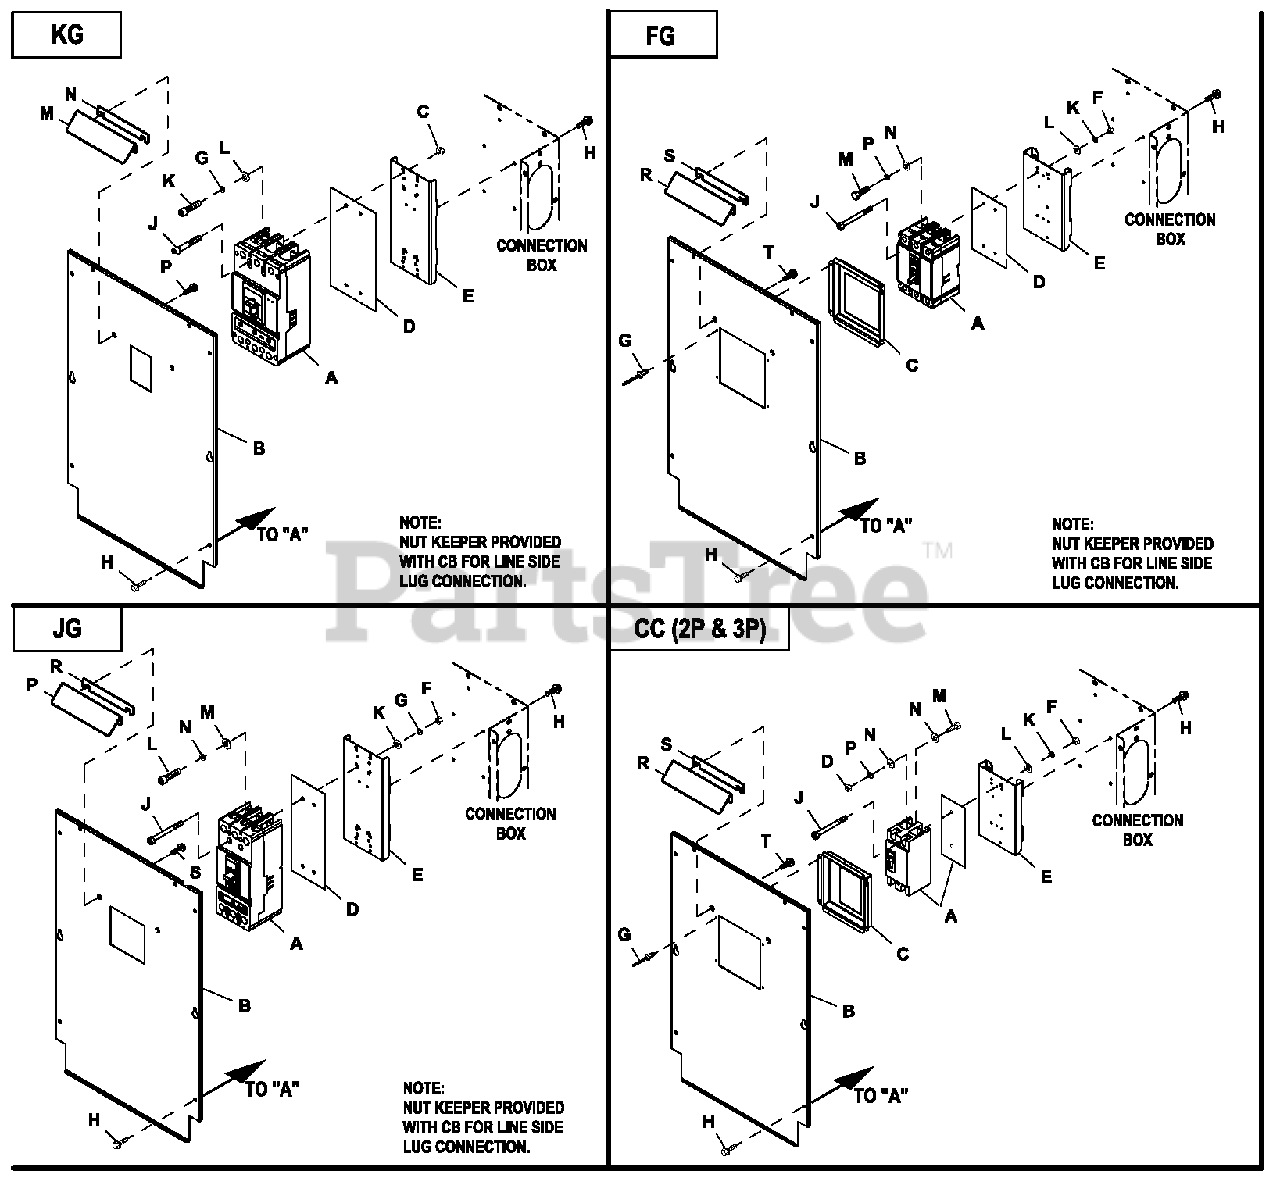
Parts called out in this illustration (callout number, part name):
A	CB 0300 3P 600V E KG LL
B	COVER CB E KG C2 CONBOX
C	NUT FLANGE M6-1.0 NYLOK
D	INSULATOR CB E 3 P KG
E	STANDOFF CB M OUNT CONBOX
G	WASHER LOCK M8-5/16
H	SCREW HWHT M 6-1 X 16 N WA Z/JS
J	SCREW SHC M 6-1.0 X 50 C8.8
K	SCREW SHC M8-1.25 X 30 C12.9
L	WASHER FLAT 5/16- M8 ZINC
M	SHIELD-S M CIRCUIT BREAKER
N	GASKET-CB SHIELD C2
P	SCREW HWHTF M 6 -1 .0X 16
A	CB 0060 3P 480V E FG LL
B	COVER CB C2 CPL
C	COVER CB DISH 3P E FG
D	INSULATOR CB 3P E TYPE CC/FG
E	STANDOFF CB BOX CONBOX
F	NUT HEX #8-32 STEEL
G	RIVET POP .125 X .275 SS
J	SCREW PPHM #8-32 X 1-3/4 ZINC
K	WASHER LOCK #8- M 4
L	WASHER FLAT #8 ZINC
M	SCREW HHC M 5-0.8 X 20 G8.8
N	WASHER FLAT #10 ZINC
P	WASHER LOCK M5
R	SHIELD-S M CIRCUIT BREAKER
S	GASKET-CB SHIELD C2
T	SCREW HWHTF M 6 -1 .0X 16
A	CB 0250 3P 600V E JG LL
B	COVER CB E JG C2 CONBOX
D	INSULATOR CB E 3P JG
E	STANDOFF CB MOUNT CONBOX
F	NUT HEX 1/4-20 STEEL
G	WASHER LOCK M 6-1/4
J	SCREW RHM 1 /4 -2 0X 3
K	WASHER FLAT 1/4-M6 ZINC
L	SCREW SHC M8-1.25 X 20 G8
M	WASHER FLAT 5/16- M8 ZINC
N	WASHER LOCK M8-5/16
P	SHIELD-S M CIRCUIT BREAKER
R	GASKET-CB SHIELD C2
S	SCREW HWHTF M 6 -1 .0X 1 6
A	CB 0175A2P 2 4 0V E CC LL
C	COVER CB DISH 2P E CC
D	NUT HEX M5-0.8 G8 CLEAR ZINC
H	SCREW HWHT M6-1 X 16 N WA Z/JS
J	SCREW RHM #8-3 2X3 -1 /4
K	WASHER LOCK#8-M4
M	SCREW HHC M5-0.8 X 20 G8.8
R	SHIELD-SM CIRCUIT BREAKER
T	SCREW HWHTF M6-1.0 X 16
